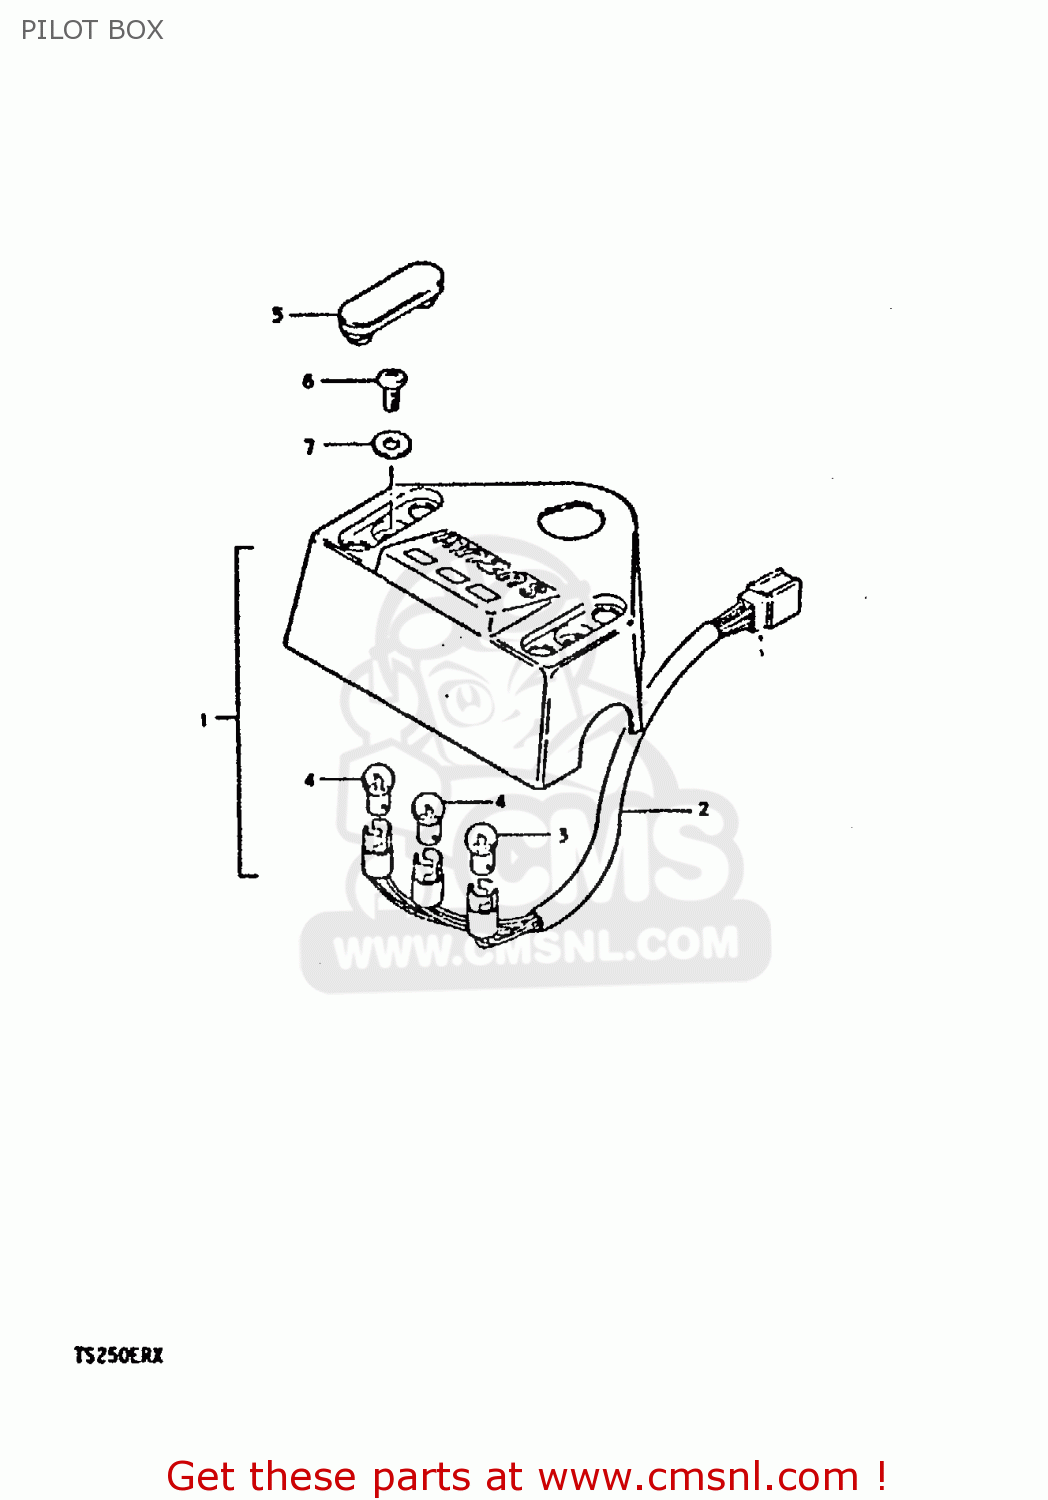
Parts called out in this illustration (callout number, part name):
1	CASE,PILOT BULB
2	SOCKET
3	BULB(6V1.7W,STANLEY,A61A)
4	BULB(6V/3W)
5	CAP,PILOT BOX BOLT
6	SCREW 6X12
7	WASHER
